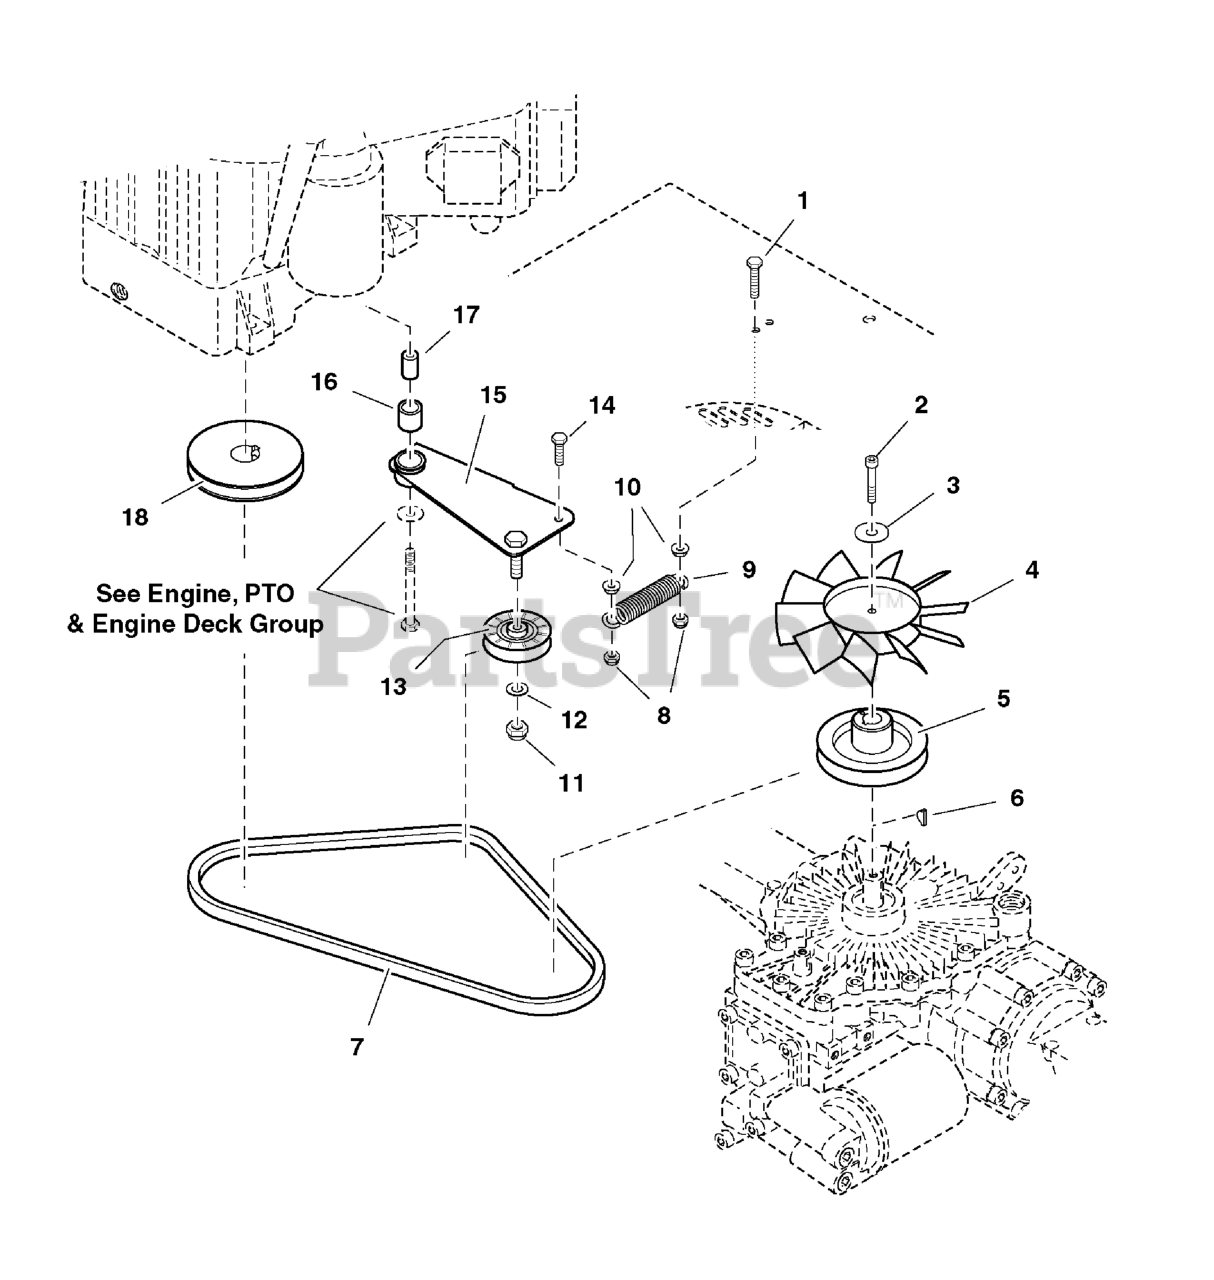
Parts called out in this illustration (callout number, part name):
1	BOLT, 5/16-18 x 1-3/4 TFL
2	BOLT, Allen Head, 1/4-20 x 1-3/4
3	WASHER, .265 x 1.50 x .109
5	PULLEY, Transmission Input
6	KEY, Hi-Pro Woodruff
7	BELT, A-Section
8	NUT, 5/16-18 Hex Nylon Lock
9	SPRING, Extension
10	NUT, 5/16-18 HEX SERRATED FLANGE (LARGE)
11	NUT, 3/8-16 HEX NYLON LOCK
12	WASHER, 3/8 SAE
13	IDLER PULLEY
14	BOLT, 5/16-18 X 1-1/4 GD5 TFL, CZ
15	IDLER ARM ASSEMBLY, Complete
16	BUSHING, Brass
17	SPACER, .32 x .75 x 1.06
18	PULLEY, Crankshaft
